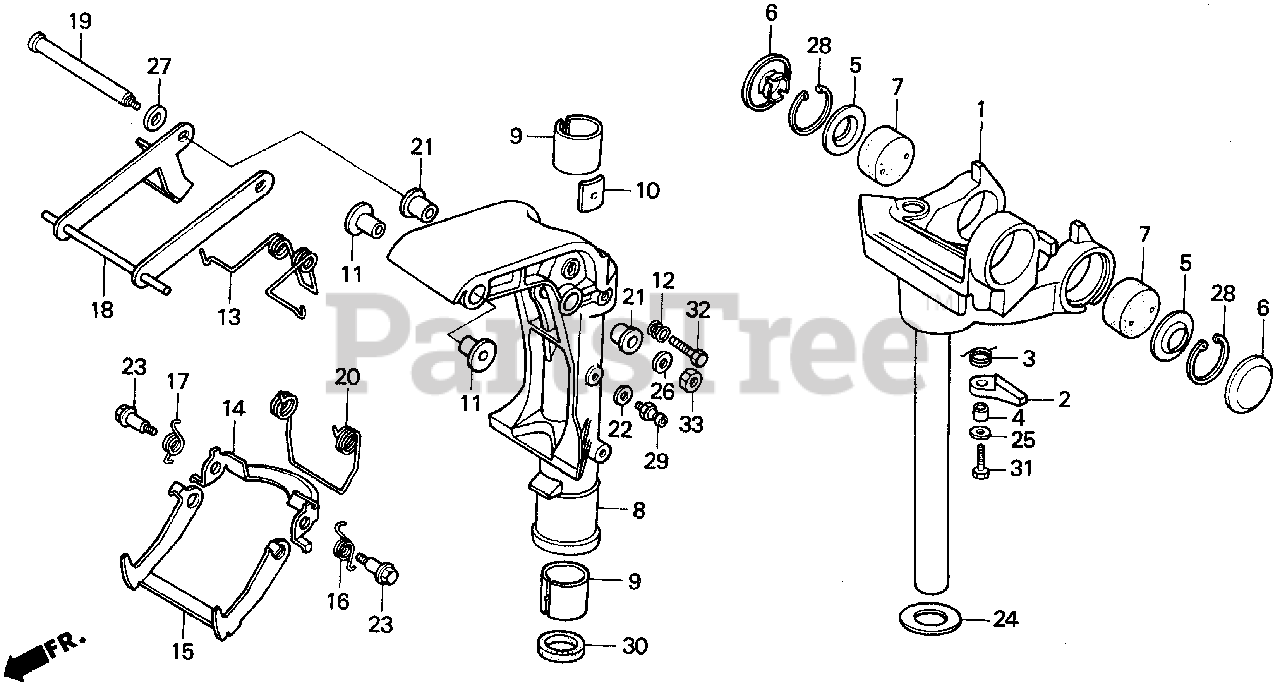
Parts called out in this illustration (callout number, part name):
1	FRAME, MOUNTING *NH282MU* (OYSTER SILVER METALLIC-U)
2	STOPPER, HANDLEBAR *NH282MU* (OYSTER SILVER METALLIC-U)
3	SPRING, HANDLE
4	COLLAR, STOPPER
5	WASHER, MOUNTING
6	CAP, MOUNTING
7	RUBBER, MOUNT (UPPER)
8	CASE, SWIVEL *NH282MU* (OYSTER SILVER METALLIC-U)
9	LINER, SWIVEL CASE
10	BLOCK, FRICTION
11	BUSH, SWIVEL CASE
12	SPRING, FRICTION ADJUSTING
13	SPRING, HOOK RETURN
14	PLATE, REVERSE LOCK
15	HOOK, REVERSE LOCK
16	SPRING, R. REVERSE LOCK
17	SPRING, L. REVERSE LOCK
18	ARM, TILT
19	SHAFT, TILT
20	SPRING, REVERSE LOCK
21	BUSH, TILT LEVER
22	WASHER (6X11)
23	BOLT, REVERSE LOCK
24	WASHER, THRUST
25	WASHER, PLAIN (6MM)
26	WASHER, PLAIN (6MM)
27	WASHER, PLAIN (10MM)
28	CIRCLIP (INNER) (40MM)
29	NIPPLE, GREASE
30	OIL SEAL (27.8X33X5) (ARAI)
31	BOLT, HEX. (6X20)
32	BOLT, SPECIAL (8X20)
33	NUT, HEX. (6MM)
